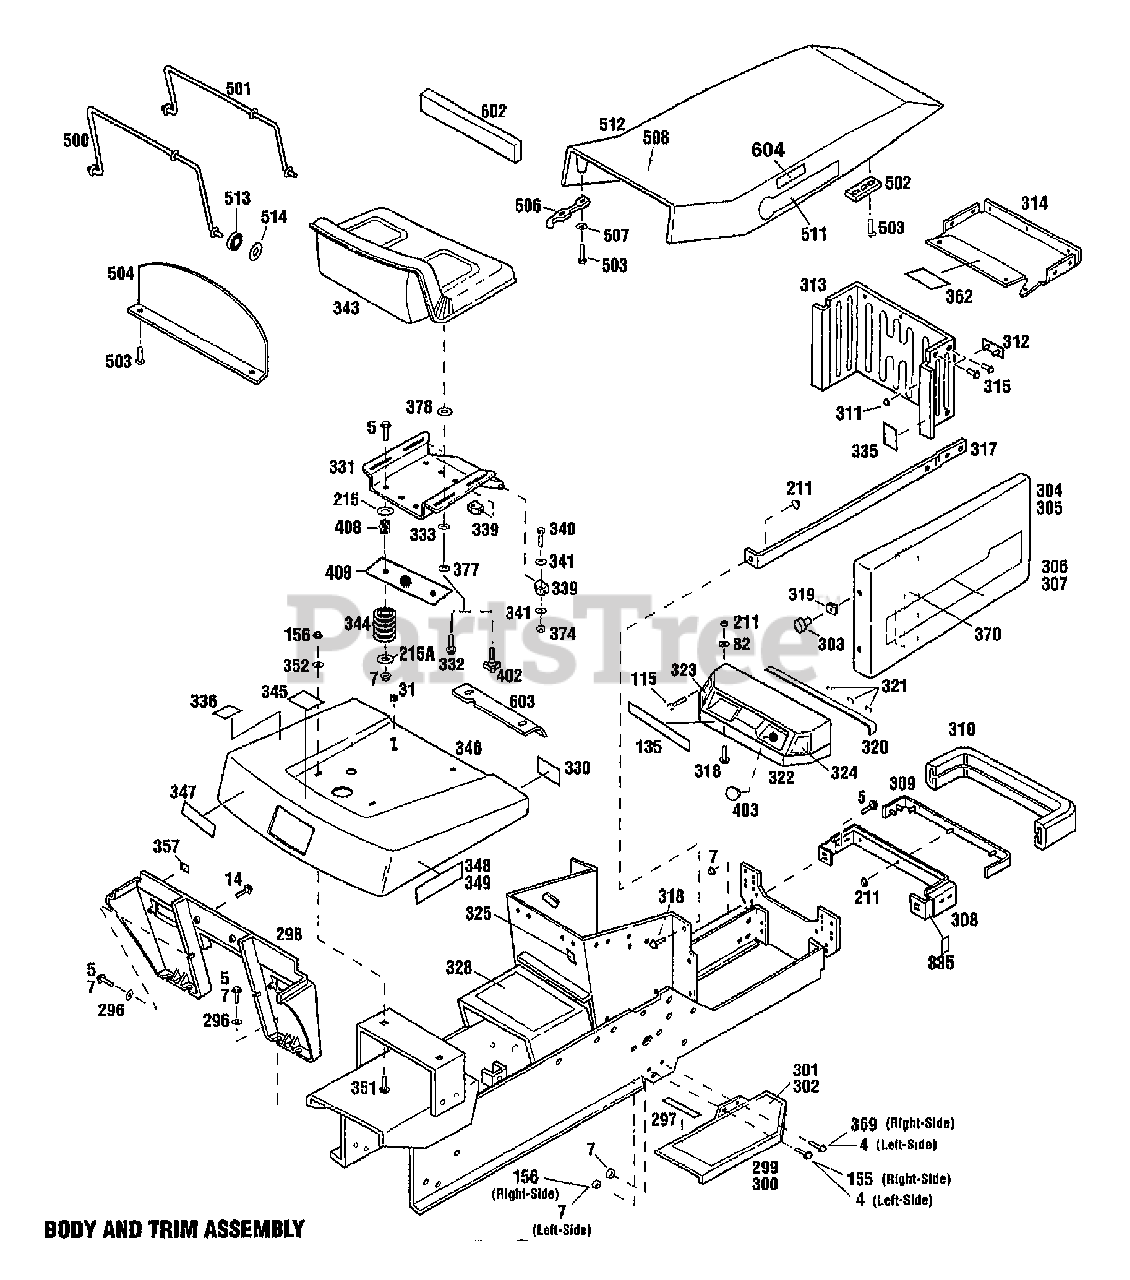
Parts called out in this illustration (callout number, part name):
5	SCR-HFLK 3/8-16X1.00 ZP
7	NUT-HFLK 3/8-16 ZP
14	SCR-HFLK 5/16-18X.75 ZP
31	GROMMET
82	WASHER-FLAT 1/4 SAE
115	SCR-PHP M6-32X.38 ZP
135	LENSE
155	SCR-TRUSS HD 5/16-18X.62
156	NUT-HFLK 5/16-18 ZP
211	NUT-HF/LK 1/4-20 ZP
215	WASHER-FLAT 1.25X.406X.179
296	WASHER-.986X.437X.083 ZP
297	CUSHION
298	SUPT-RUNNING BOARD
299	FOOTREST-LH
300	FOOTREST-RH
301	PAD-FOOTREST LH
302	PAD-FOOTREST RH
305	COVER-RH
306	DECAL-SIDE COVER LH
307	DECAL-SIDE COVER RH
308	ASSM-GRILLE SUPT
309	ASSM-BUMPER STRAP
310	BUMPER-EXTRUSION
311	NUT-PUSH
312	PLATE-LOGO
313	GRILLE-TRACTOR
314	CAP-GRILL
314	CAP-GRILLE
315	RIVET-POP
317	SUPPORT
318	SCR-HH 1/4-20X.625
319	NUT-SPEED #10
320	PAD-HOOD
322	PANEL-INSTRUMENT
323	DECAL-CHOKE
324	DECAL-THROTTLE
325	DECAL-IGNITION
328	DECAL-OPERATING INST
330	DECAL-AMERICAN LEGEND-LRG
331	ASSM-SEAT SUPPORT
332	SCR-SHLDR 3/8-16X.25 G5ZP
333	WASHER-1.375X.523X.059
339	BLOCK-PIVOT
340	SCR-HH 5/16-18X1.5 G5 ZP
341	WASHER-1.5X.343X.104
343	SEAT (TRACTOR)
344	SPRING-COMPRESSION
345	DECAL-FUEL
346	FENDER-REAR
347	DECAL-LOGO FENDER
348	DECAL-LEFT FENDER
349	DECAL-RIGHT FENDER
351	BOLT-CARR 5/16-18X.63 ZP
352	WASHER-1.25X.343X.059
357	BUTTON-RUBBER
362	DECAL-HOT SURFACE
369	SCR-HH 3/8-16X.75 G5 ZP
370	BLOCK-SEALING
374	NUT-TOP/LK 5/16-18 ZP
377	WASHER-BOW .74X.52X.01
378	WASHER-FLAT
408	SPRING-COMPRESSION
500	LINK-HINGE
501	LINK-HINGE
502	RETAINER-HINGE LINK
503	SCR-SEMS MACH
504	BAFFLE-HOOD
506	LATCH-RUBBER
507	WASHER-.88X.2X.059
508	DECAL-SERVICE INST
511	DECAL-LOGO
512	ASSM-HOOD
513	GROMMET
514	RETAINER
602	BLOCK-SEALING
603	BRKT-DOUBLER
